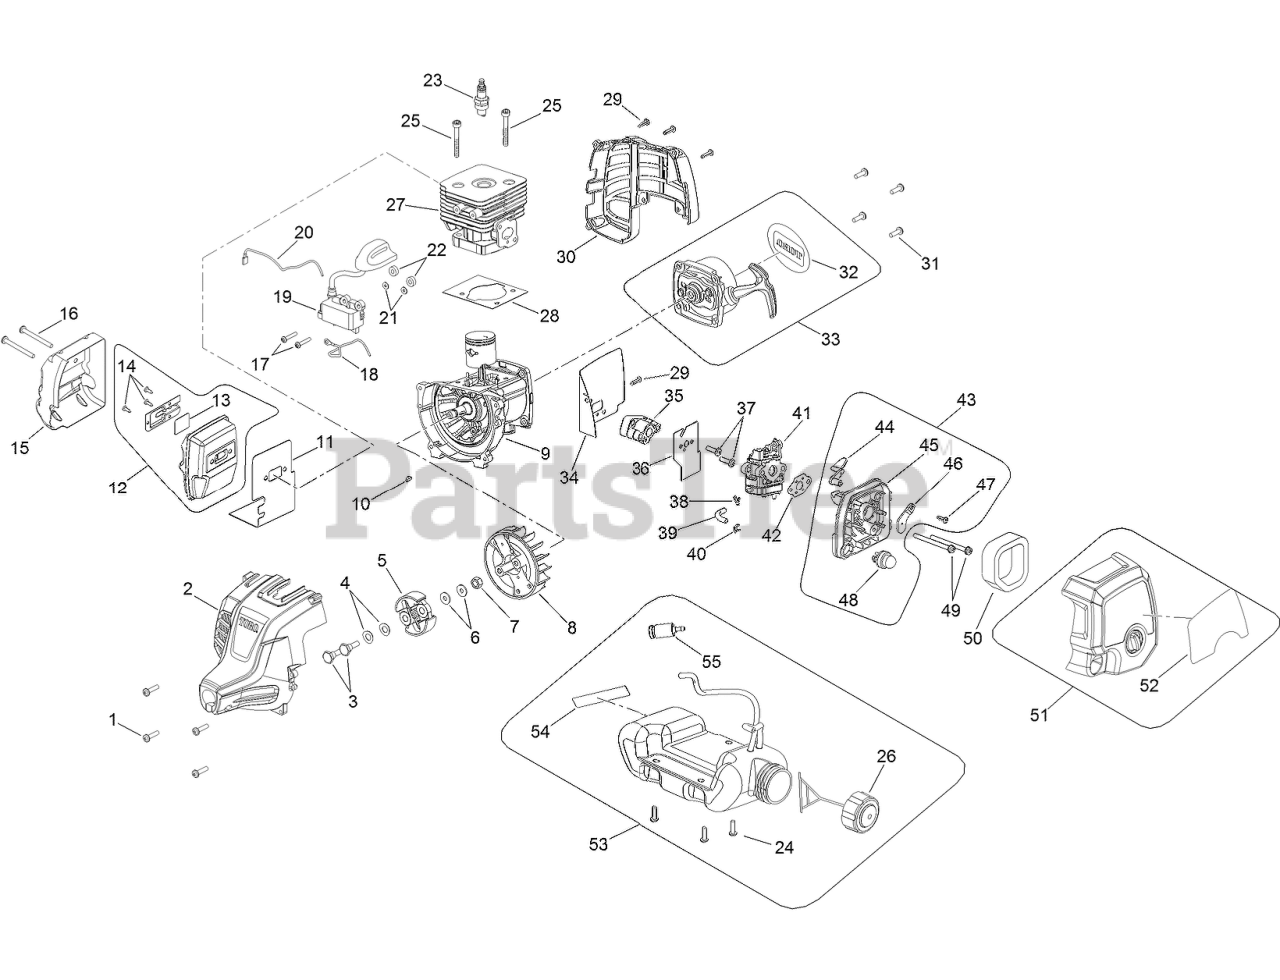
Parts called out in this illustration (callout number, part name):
1	SCREW-PAN HD
2	HOUSING-ENGINE, FRONT
3	SCREW-CLUTCH
4	WASHER-CURVED
5	CLUTCH ASM
7	NUT-ROTOR
9	CRANKCASE ASM
10	KEY-WOODRUFF
11	GASKET-MUFFLER
12	MUFFLER ASM
14	SCREW-PAN HD
15	SHIELD-HEAT
16	SCREW-PAN HD
17	SCREW AND WASHER
18	WIRE-LEAD, RED
19	COIL BOOT ASM
20	WIRE-LEAD, BLACK
23	SPARK PLUG
25	SCREW-SOCKET HEAD
26	CAP-FUEL
27	CYLINDER
29	SCREW
30	HOUSING-ENGINE, REAR
31	SCREW-PAN HD
32	PLATE-LOGO
33	RECOIL STARTER AND STARTER CUP ASM
34	INSULATOR-GASKET
35	INSULATOR-DAM, HEAT
37	SCREW AND WASHER
38	CLIP-HOSE
39	LINE-FUEL
40	CLIP-HOSE
41	CARBURETOR ASM
42	GASKET-CARBURETOR
43	FILTER HOUSING ASM
44	LEVER-CHOKE
45	PLATE-CARBURETOR
46	PLATE-CHOKE
47	SCREW-PAN HD
48	PRIMER ASM
49	SCREW-PAN HD
50	ELEMENT-FILTER, AIR
51	COVER ASM
52	DECAL-START
53	FUEL TANK AND CAP ASM
54	LABEL-COMBUSTION
55	FILTER-FUEL
